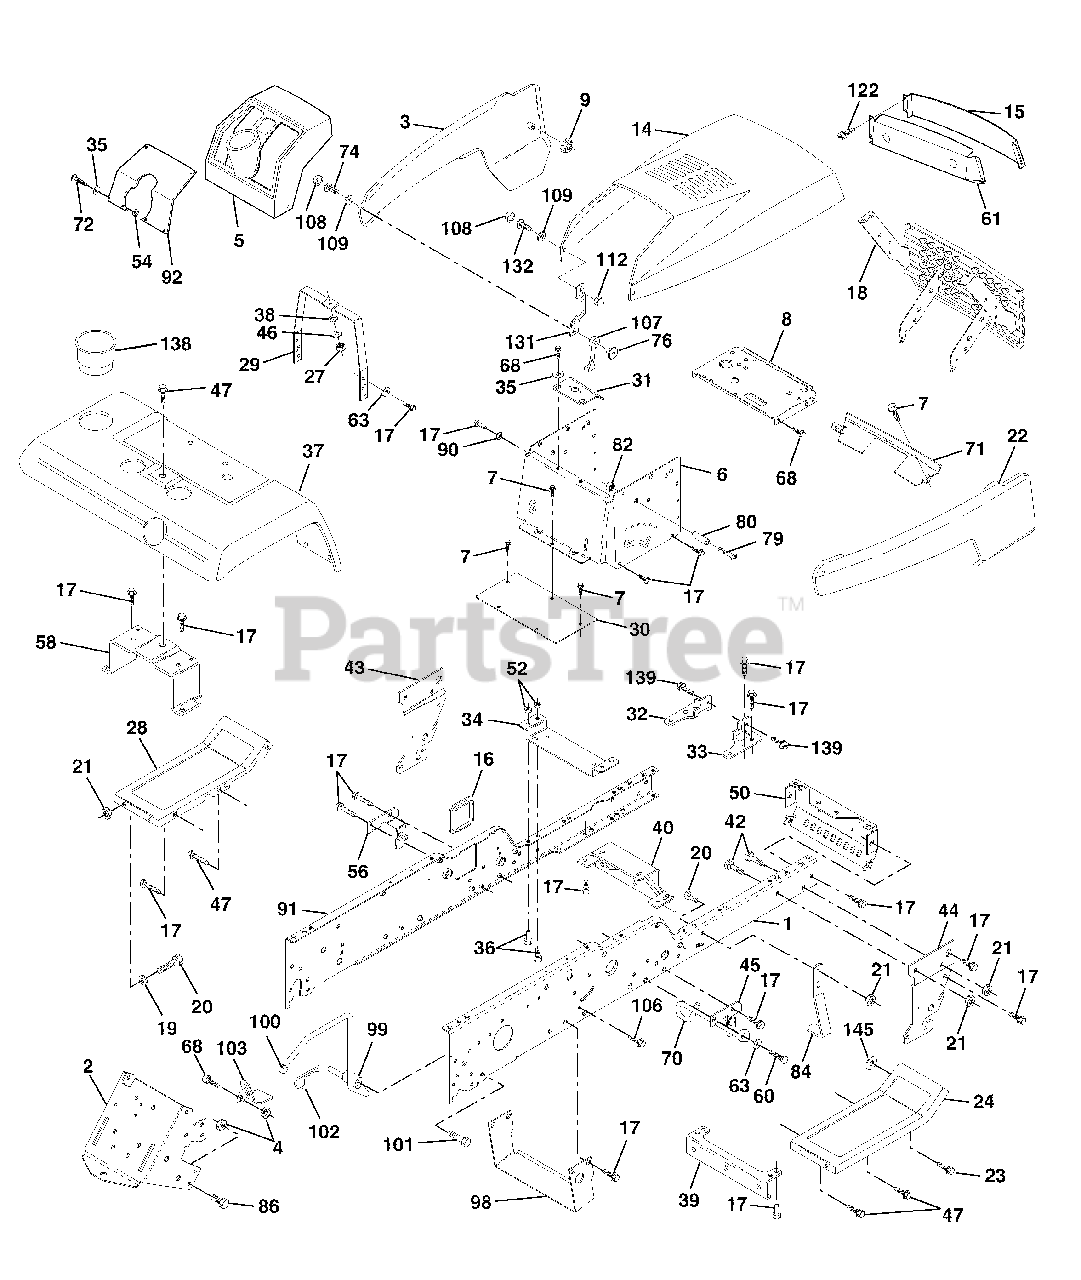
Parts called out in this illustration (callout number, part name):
1	Rail, Frame RH
2	Drawbar,Gt
3	Panel Asm., Side LH
4	Nut, Lock Hex 7/16 Unc
5	Dash, Plastic Black
6	Dash, 1PCS, Lower
7	Screw, Thd Cut 1/4-20 x 1/2
8	Support, Battery
9	Nut, Pal
14	Hood Asm., Pnt
15	Lens, Headlight Bar
16	Cover, Access
17	Screw, Hex Wsh Thdrl 3/8-16 x 3/4
19	Washer 13/32 x 13/16 x 12 Ga.
20	Bolt, Fin Hex 3/8-16 x 1
21	Nut, Crownlock 3/8-16
22	Panel Asm., Side RH
23	Screw Thdrol 3/8-16 x 1
24	Footrest, RH
27	Nut, Fin Hex 1/4-20
28	Footrest, LH
29	Bracket, Support Dash
30	Saddle
31	Bracket Supt 1-pc Vgt Steering
32	Bracket, Frame Pivot Lh
33	Bracket, Frame Pivot Rh
34	Bracket, Engine Support Rear
35	Washer 11/32 x 11/16 x 16 Ga.
36	Bolt, Fin Hex 5/16-18 x 3/4
38	Washer, Lock 1/4
39	Bracket, Axle Front
40	Bracket, Support Axle/Engine
42	Bolt Rdhd Sqnk 3/8-16 Unc x 1
43	Bracket, Spnsn Front Lh
44	Bracket, Spnsn Front Rh
45	Bracket Asm., Susp Chassis Rh
46	Washer 9/32 x 3/4 x 16 Ga.
47	Screw Thdrol 3/8-16 x 1/2
50	Bracket, Chassis Front
52	Nut, Crownlock 5/16-18
56	Bracket Asm., Susp Chassis Lh
58	Bracket Asm., Fender
60	Screw Thdrol 3/8-16 x 1-1/4
61	Beze. Asem.
63	Washer 13/32 x 1 x 14 Ga.
68	Screw, Thdrol 5/16-18 x 1/2
70	Guide, Belt Mid Span
72	Screw, Mach Trhd 5/16-18 x 3/4
74	Screw, Machine #10-24
76	Nut, Weld #10-24
79	Screw, Machine #10-24 x 1/4
80	Spacer, Split
84	Stop, Over Center Mower
86	Bolt, Fin Hex 7/16-14 Unc x 1
90	Washer, Lock External Tooth 3/8
91	Rail, Frame Lh
92	Plate, Silkscreen Dash
98	Bracket Chassis Skid
99	Rod Asm. Bypass
100	Cap Brake Parking Red
101	Screw Thdrol. 3/8-16 x 1-3/4
102	Retainer Spring 1"
103	Bracket Lock Bypass
106	Screw Thdrol Hex Head Zinc
107	Latch, Chute Blk
108	Cap, Snap Black
109	Cap, Washer Snap Nat
112	Nut, Acorn, Hex #10-24
122	Screw Hex Wshd 8-18 x 7/8
131	Bracket Support Hood/Panel YP
132	Screw Truss Hd #10-24 x 3/8
138	Cupholder YTGT Black
139	Bolt Shoulder 5/16-18
